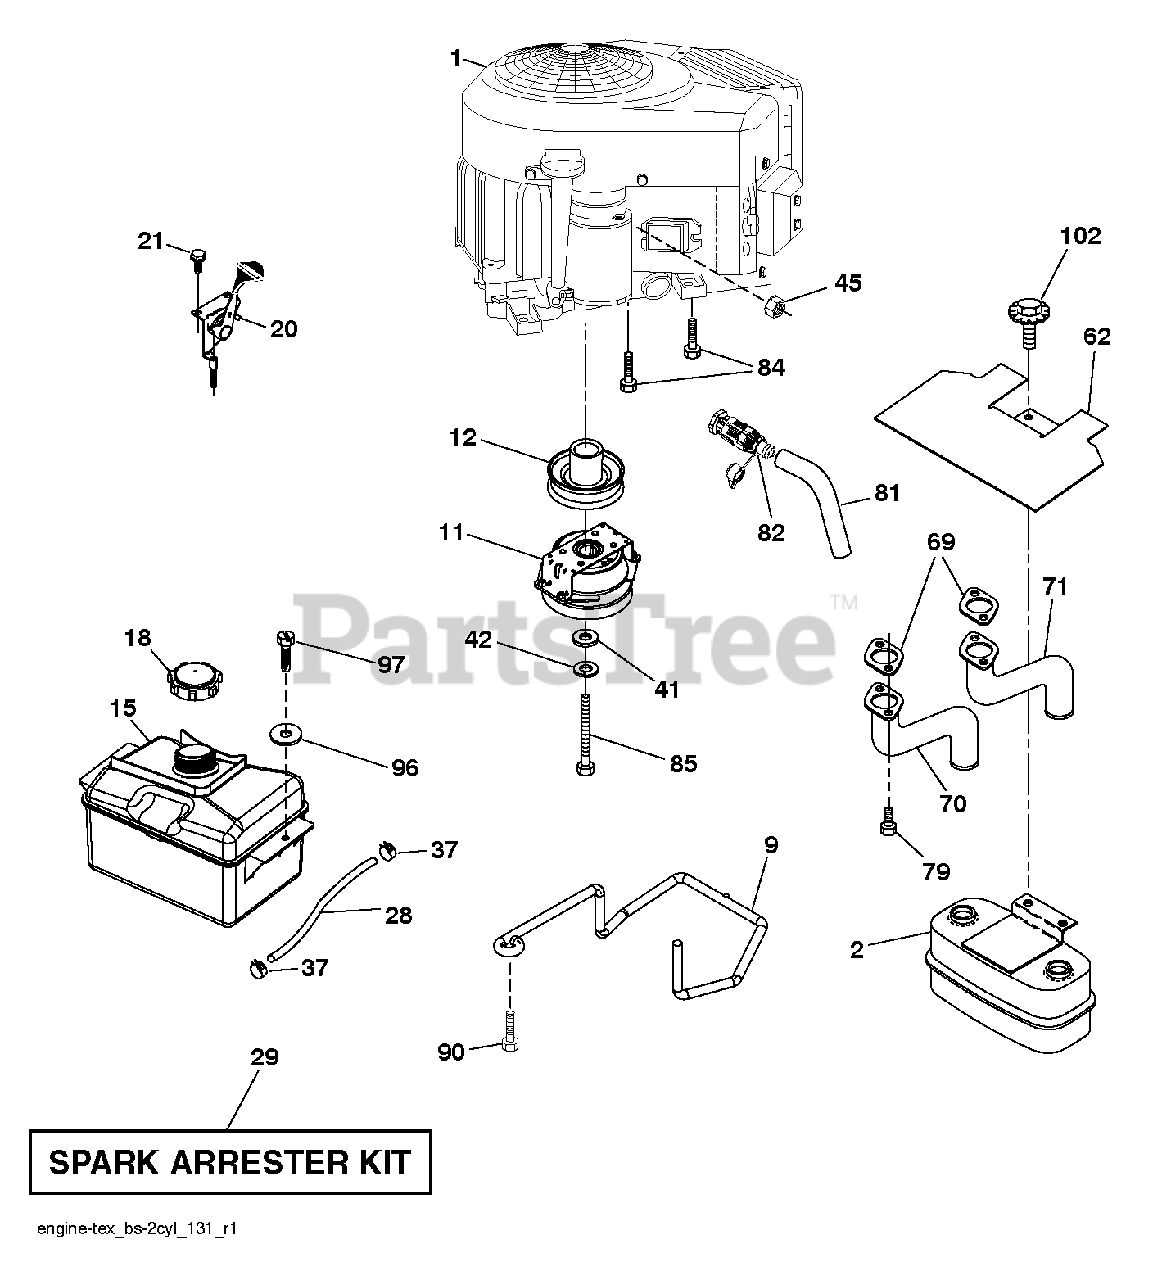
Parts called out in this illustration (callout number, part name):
2	MUFFLER.ASM.TWN.EXTNDED.DFLCTR
9	KEEPER BELT ENGINE
11	CLUTCH.OGURA.5.0PD.GT1.5A-EH07
12	PULLEY.ENGINE.TUFFTORQ
15	TANK.ASM.FRNT.DAPCO.E10
18	CAP ASM.FUEL.2.25"FR.
20	THROTTLE.COBRA.38"READSTART.BK
21	SCREW.#10 X 0.750.BOS
28	LINE.FUEL.20
29	KIT.SPARK ARRESTOR 794945 B&S
37	HOSE CLAMP
42	LOCKWASHER
45	NUT
62	SHIELD.HEAT.MUFFLER
69	GASKET.MUFFLER
70	EXHAUST.TUBE.LH.BS/TWIN
71	EXHAUST.TUBE.RH.B&S.TWIN.INTEK
79	SCREW.SOCKET.HEAD.5/16-18
81	TUBE, DRAIN OIL ASM.
82	VALUE.OIL.DRAIN
84	SCREW.3/8-16
85	BOLT HEX 7/16-20 X 3.75 GR. 5
90	SCREW 3/8-16X1
96	WASHER
97	SCREW HEXWSHR 1/4-20X3/4
102	SCREW
